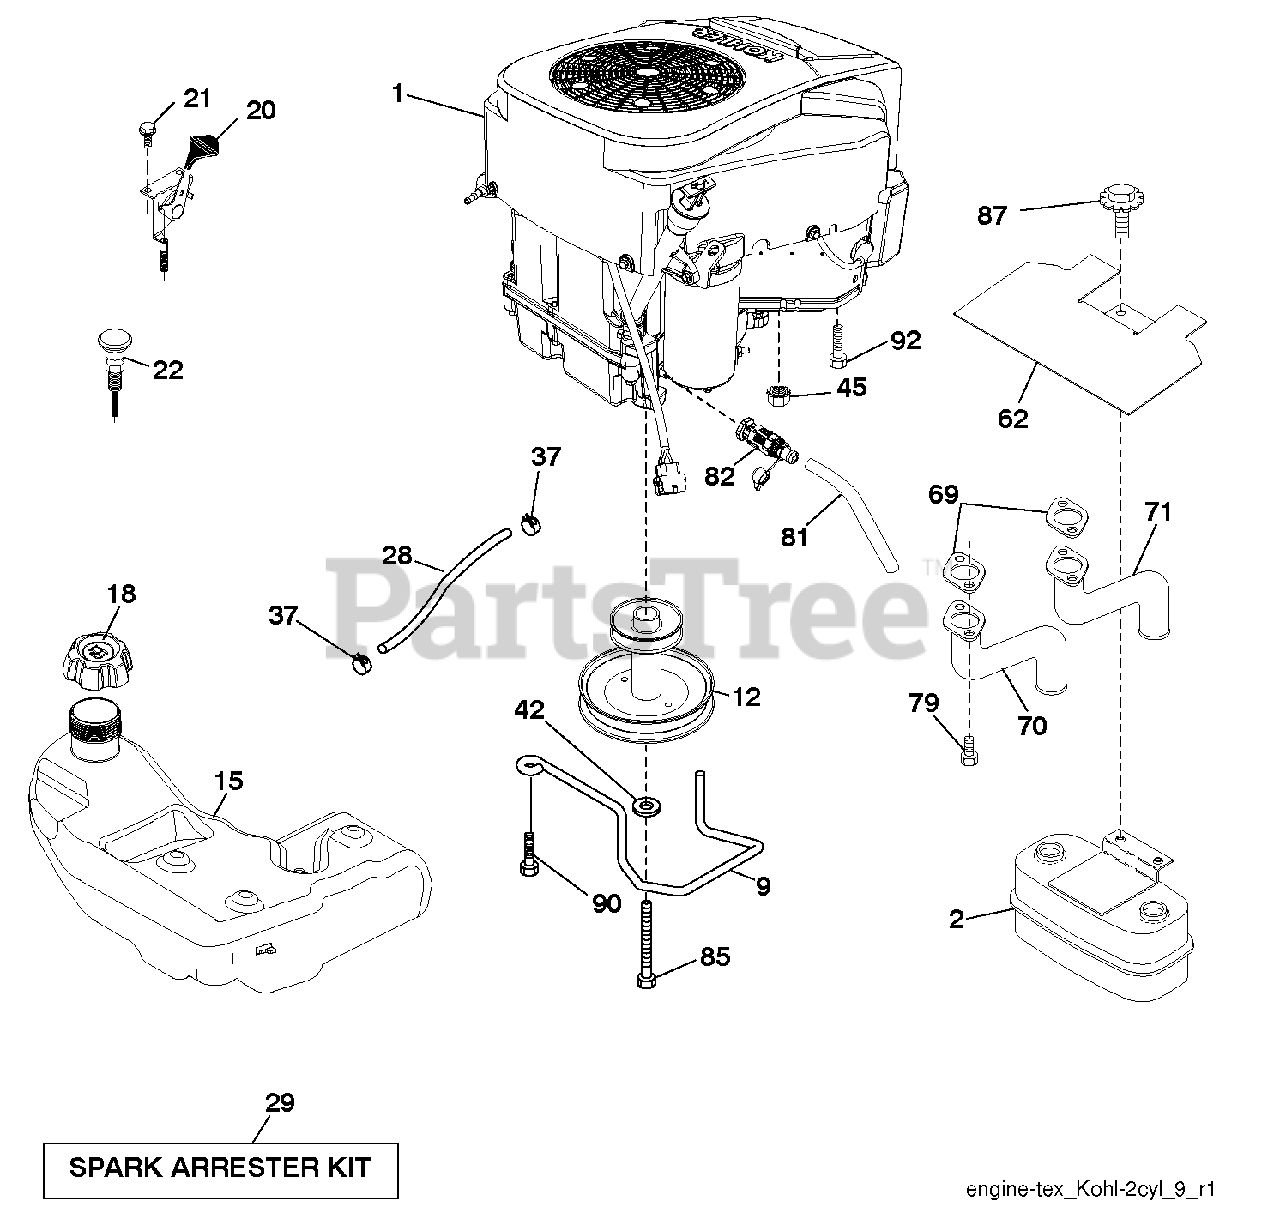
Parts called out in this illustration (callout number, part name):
2	MUFFLER.ASM.TWN.EXTNDED.DFLCTR
9	KEEPER.BELT.ENGINE.4.2
12	PULLEY ENGINE
15	TANK.ASSY.3.GAL.EPA
18	CAP.ASM.FL.RITCH.3"E10.SYM.498
20	THROTTLE CONTROL
21	SCREW.#10 X 0.750.BOS
22	CONTROL.CHOKE.ERGO.PUSH-IN.BLA
28	REPL BY 532 00 85-43
29	KIT.SPARK ARRESTOR 794945 B&S
37	HOSE CLAMP
42	LOCKWASHER
45	NUT
62	SHIELD.HEAT.MUFFLER
69	GASKET.EXHAUST.KOHL.CV18-CV26
70	RP.PIPE-EXHAUST LH
71	RP.PIPE-EXHAUST RH
79	SCREW.SOCKET HD.5/16-1
81	TUBE, DRAIN OIL ASM.
82	VALUE.OIL.DRAIN
85	BOLT HEX 7/16-20X4-1/4"
87	Bolt, 5/16-18 X 1-3/4
90	SCREW 3/8-16X1
92	SCREW 3/8-16X1
